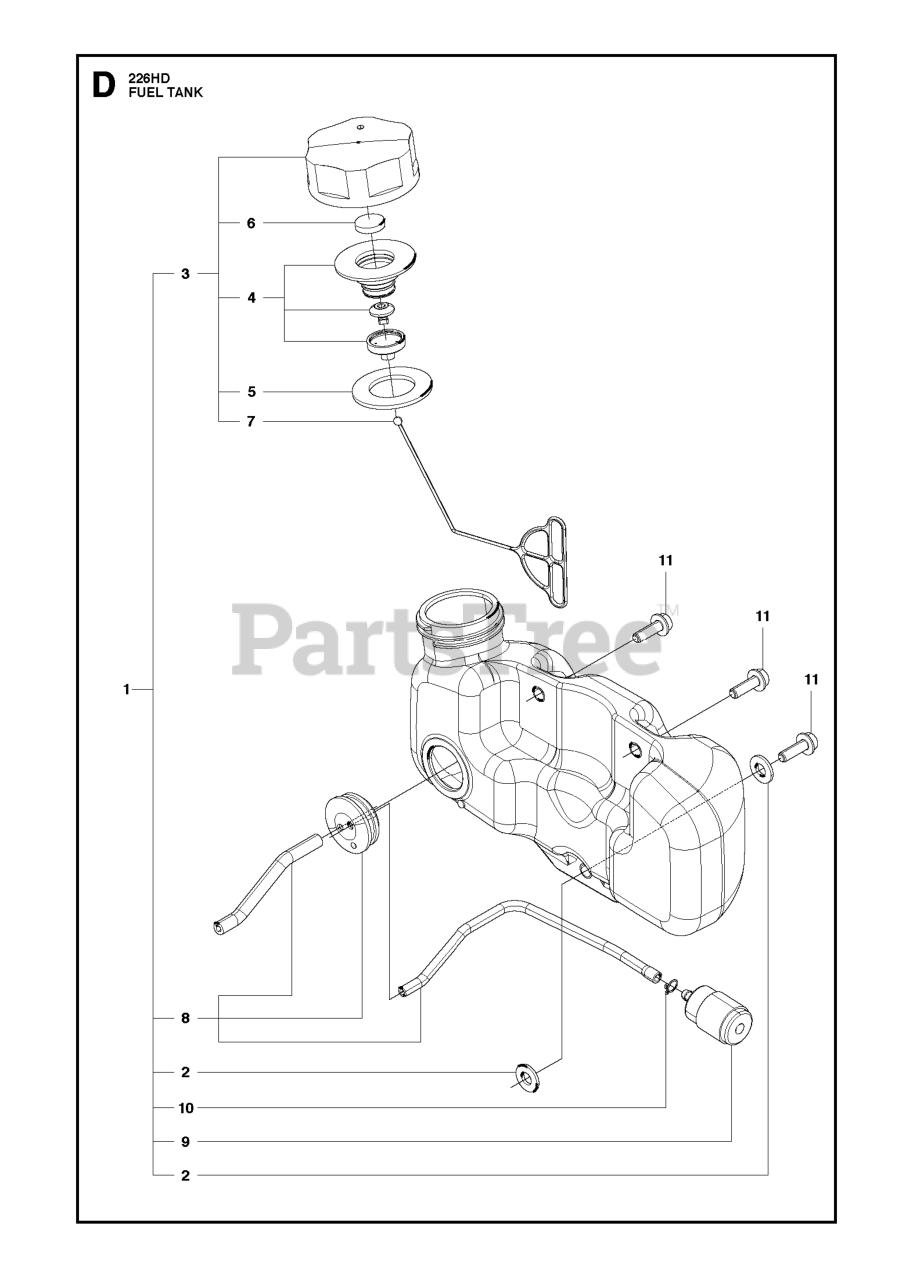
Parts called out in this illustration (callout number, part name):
1	TANK ASSY EU 848F018503
8	PIPE COMPLETE
8	PIPE COMP
9	FILTER
